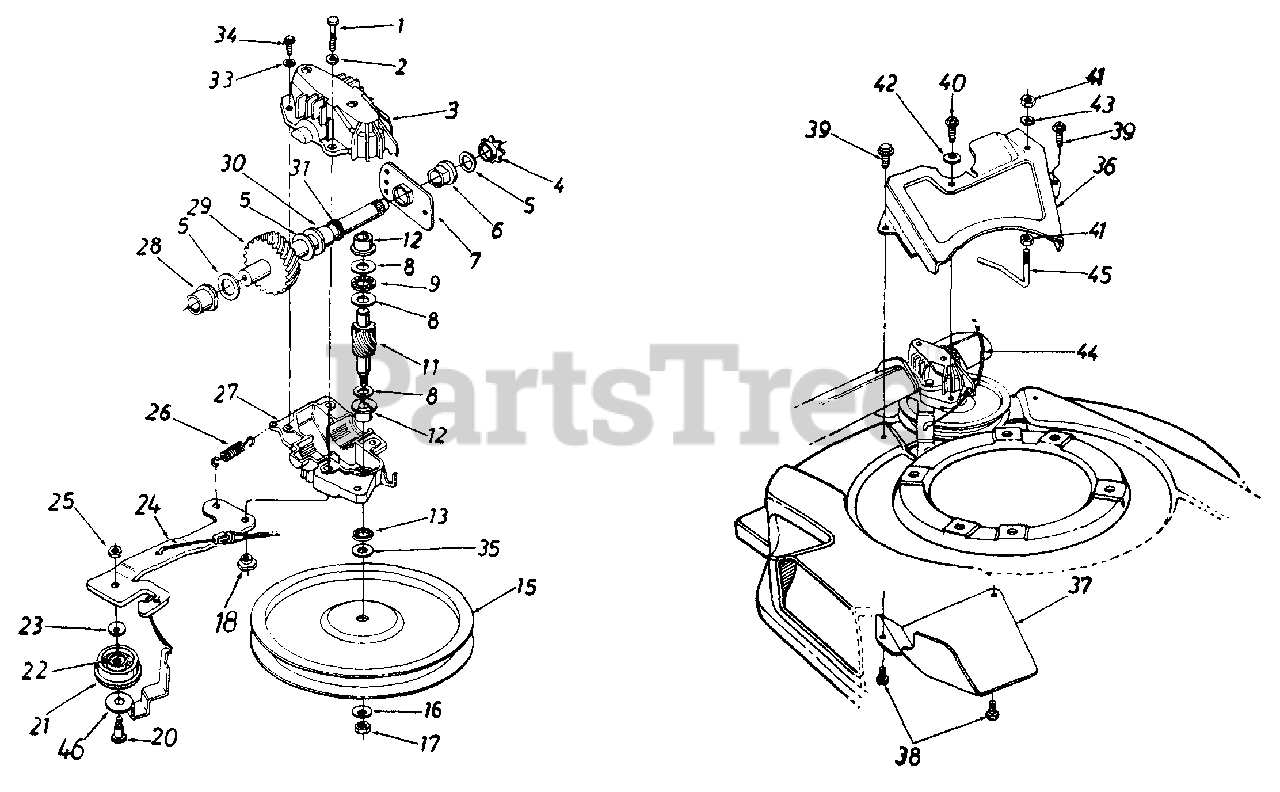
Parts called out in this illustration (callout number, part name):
1	Hex Patch Bolt 1/4-20 x 1.25" Lg.
2	L-Wash. 1/4" I.D.
3	Upper Hsg. Half
4	#48 Sprocket 7 Tooth x 1/2 Pitch
5	Fl-Wash. 5/8" I.D. x .030
6	Hex Flange Brg. .631" I.D.
8	Thrust Wash. .382" I.D. x .70" O.D.
9	Thrust Bearing .375" I.D. x .812" O.D.
11	11 Tooth Helical Gear
12	Flange Bearing
15	Fl-Pulley 5.06" I.D.
16	Bell-Wash. .265" I.D. x .75"
17	Hex Nut 1/4-28 L.H. Thd.
18	Shld. Spacer .375" Dia. x .170
20	Shld. Bolt .375" Dia. x .40"
21	Fl-Idler Plastic 1.50" Dia.
22	Needle Brg. .375" x .375"
23	Bell-Wash. .265" I.D. x .75"
24	Idler Brk't. Ass'y.
25	Hex Patch L-Nut 1/4-28 Thd.
26	Extension Spring 1.12" Lg.
27	Lower Hsg. Half
28	Flange Bearing .56 Dia.
30	Flange Bearing .629 Dia.
31	Oil Seal .625 Dia.
33	L-Wash. #10 I.D.
34	Hex B-Tap Scr. #10 x .62"
35	Hex Washer .26" x .88"
39	Hex AB-Tap Scr. 1/4 x .50" Lg.
40	Hex B-Tap Scr. 1/4 x .62" Lg.
41	Hex Nut 1/4-20 Thd.
42	Bell-Wash. .265" I.D. x .75"
43	L-Wash. 1/4" I.D.
44	S.P. Cable - 48" Lg.
45	S.P. Belt Guards
46	Belt Keeper
